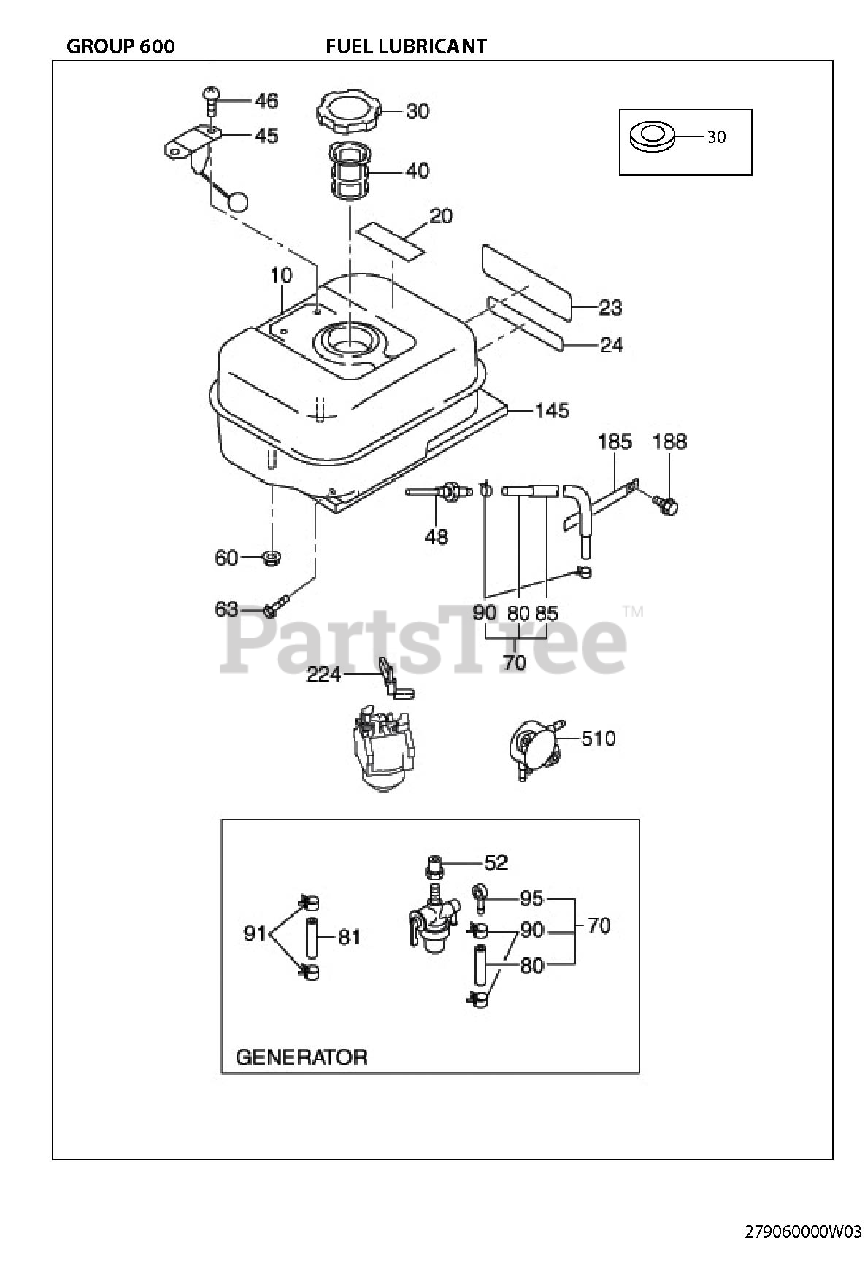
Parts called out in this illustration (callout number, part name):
20	LABEL(WARNING)
30	FUEL TANK CAP CP
90	HOSE CLAMP
224	CHOKE LEVER CP
